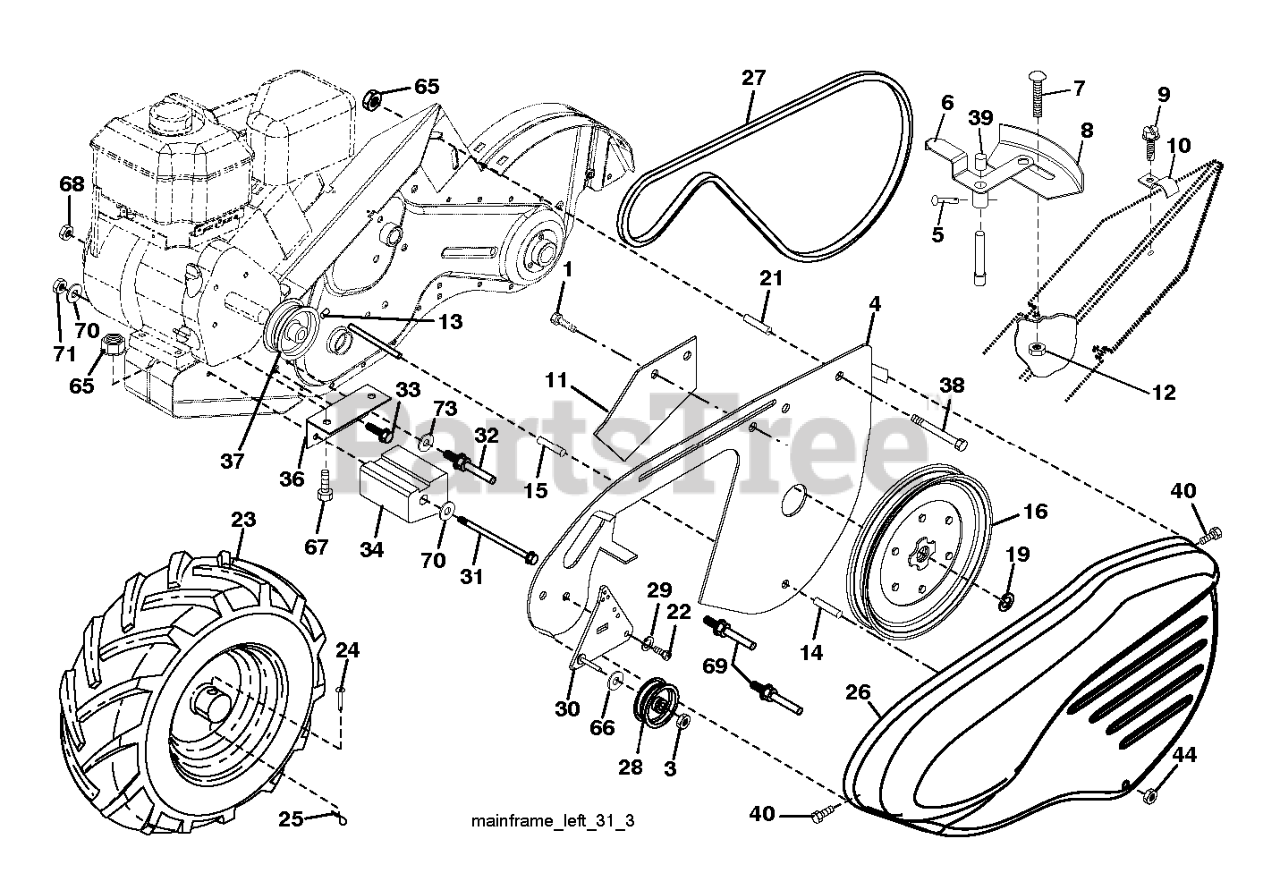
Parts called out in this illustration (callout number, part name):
1	SCREW.HEX.WASH.HD.TAPPING
3	LOCKNUT
4	SHIELD.INNER.BELT.GUARD.RT.BLA
5	PIN.SPIROL.FLARED
6	LEVER.ASM.SHIFT.RED
8	PANEL.INDICATOR.SHIFT.BLACK.
9	TAPPING SCREW
10	CLIP.PLATED
11	GUARD.RT TILLER.CRT/DRT.CE
12	NUT
14	SPACER-SPLIT.327 X .42
16	SHEAVE, TRANSMISSION
19	RETAINING RING LT
21	SPACER SPLIT .420 X .327
23	WHEEL.ASM.DRT.13X5-6.LT.SILVER
24	RIVET
25	RETAINER M
26	GUARD.BELT.TILLER.ORANGE
27	V-BELT
28	PULLEY-IDLER TI
30	BRACKET.IDLER.ASM.LONG
31	BOLT.FIN.HEX.3/8-16UNC X 11.5
32	SHIFT ARM CRT
33	BOLT
34	COUNTERWEIGHT.LH
36	BRACKET.REINFORCEMENT.LH.PNT
37	PULLEY ENGINE 4L 2.50
38	BOLT
39	CAP.PLUNGER.BLACK
40	SCREW.HEX.WSH.SLT.#10-24X.50
44	NUT.71038.31-18.HEX.NYLOCK
65	LOCKNUT-FLANGE 5/16-18
66	WASHER
67	BOLT, HEX 5/16-18X1-3/4
69	KEEPER.BELT.ENGINE
70	WASHER
73	WASHER
